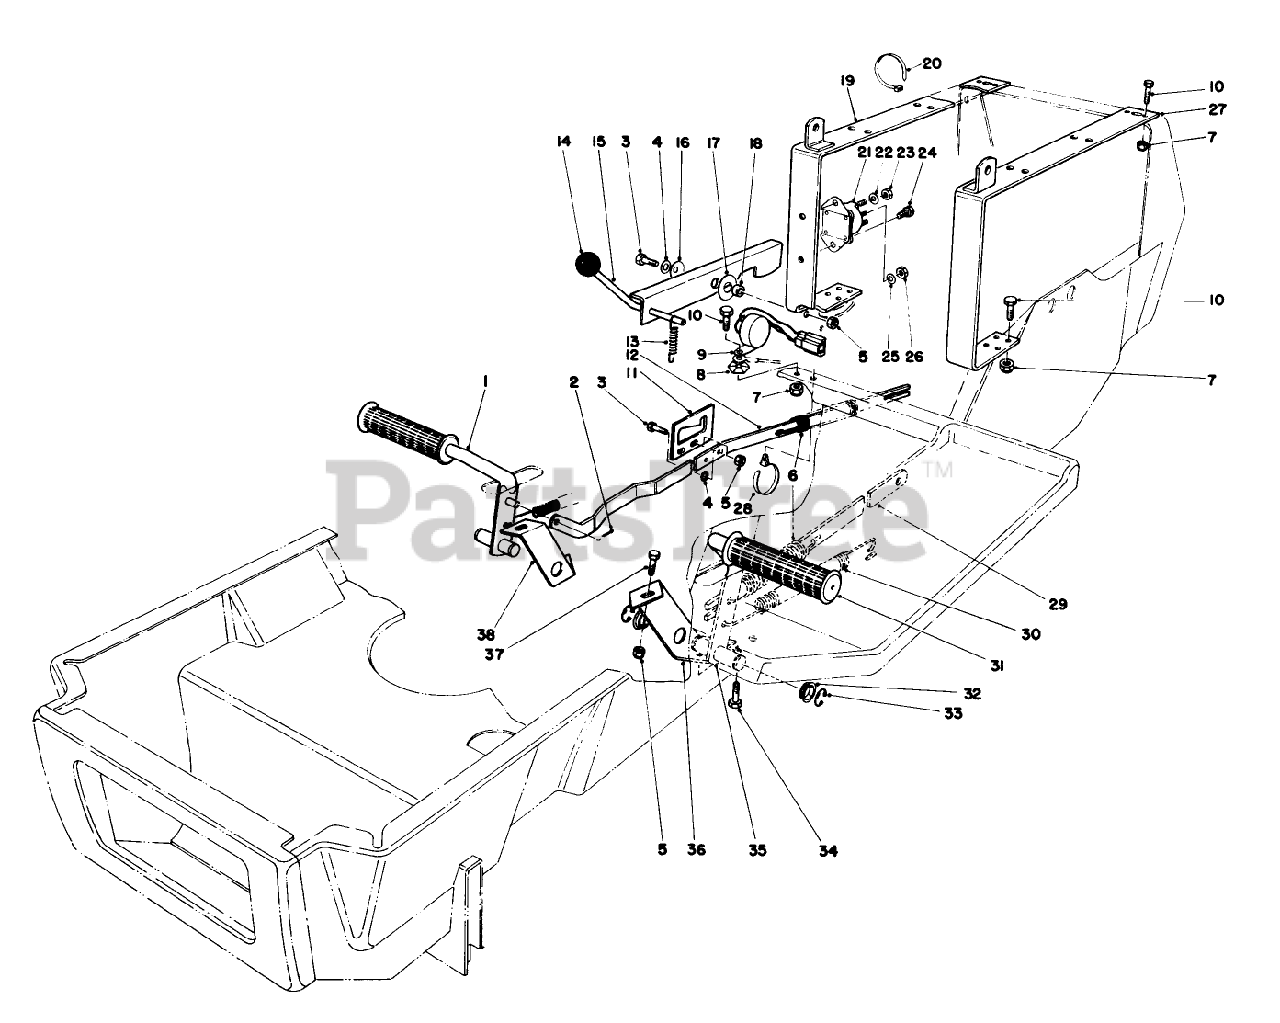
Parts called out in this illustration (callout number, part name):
2	PIN-COTTER
3	SCREW-HH
4	WASHER-PLAIN
5	NUT-LOCK, NI
7	NUT-LOCK, NI
10	SCREW-HH
16	WASHER-BELLEVILLE
17	WASHER-PLASTIC
20	TIE-CABLE
21	SOLENOID
22	WASHER-LOCK
23	NUT-JAM, BRASS
24	SCREW-HWH
25	WASHER-LOCK
26	NUT-HEX
28	TIE-MOUNT, PUSH
30	SPRING-EXTENSION
33	E-RING
34	SCREW-THD ROLL, HWH
35	CLUTCH PEDAL WA *BO
37	SCREW-HH
